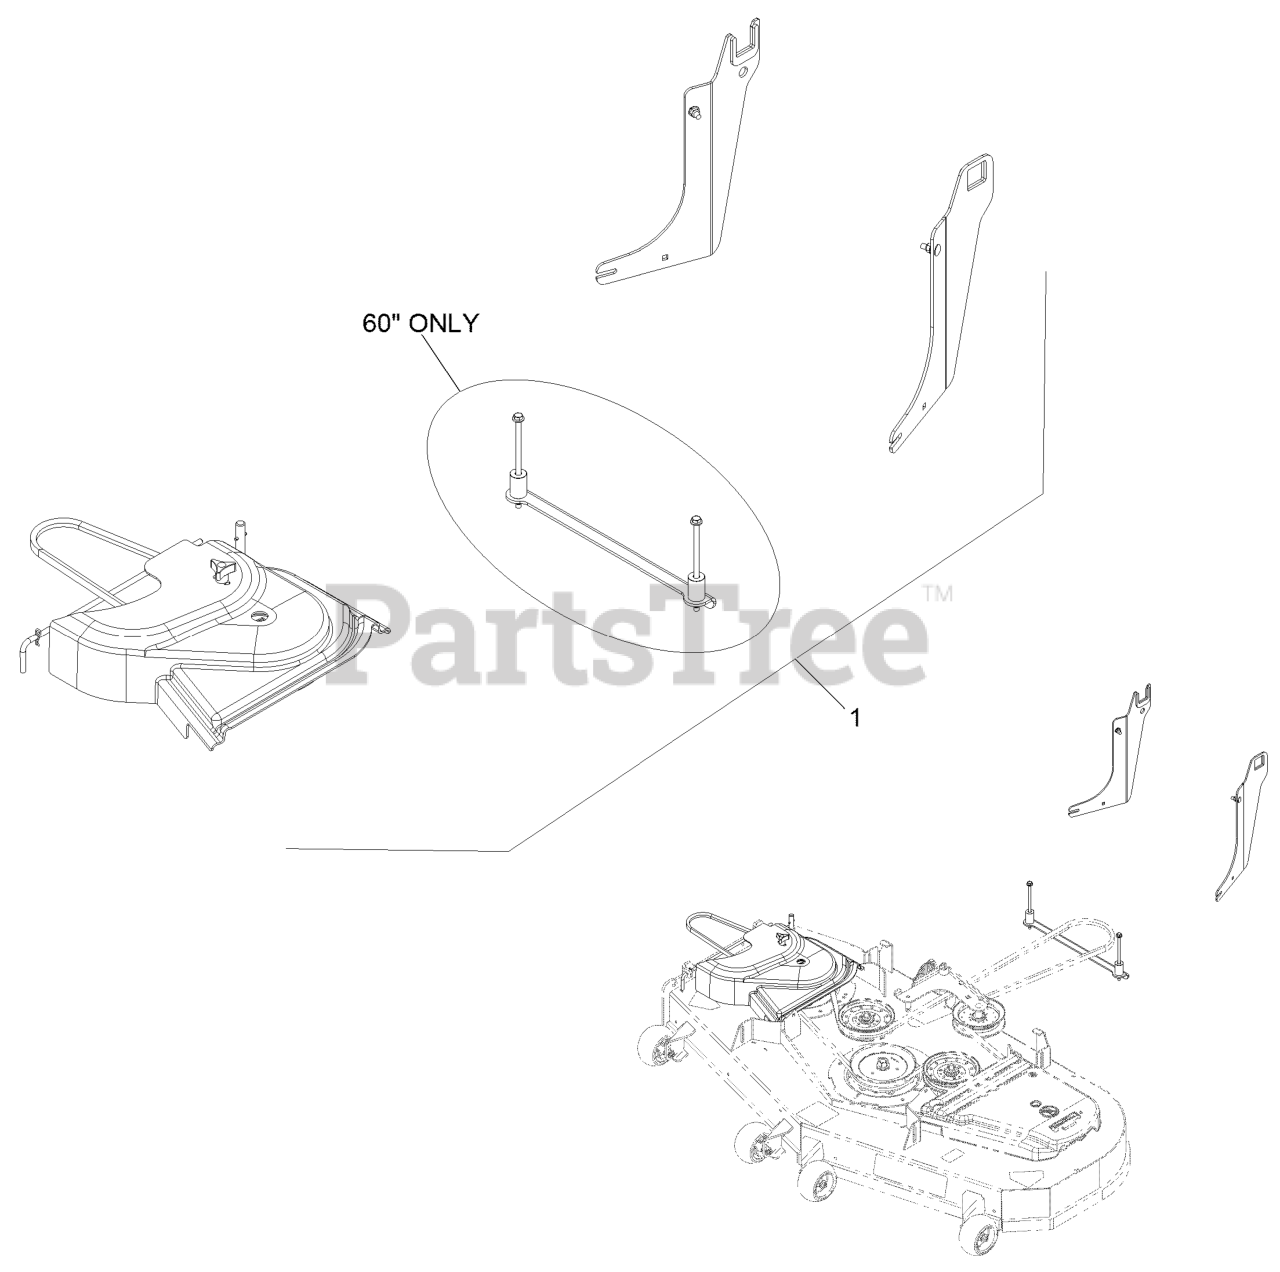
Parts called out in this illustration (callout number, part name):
1	Kit-Completing Qsp 44 Uve
1	Kit-Completing Qsp 48 Uve
1	Kit-Completing Qsp 52 Uve
1	Kit-Completing Pi 44 Uve
1	Kit-Completing Pi 48 Uve
1	Kit-Completing Pi 52 Uve
1	Kit-Completing Pn60 Uve
